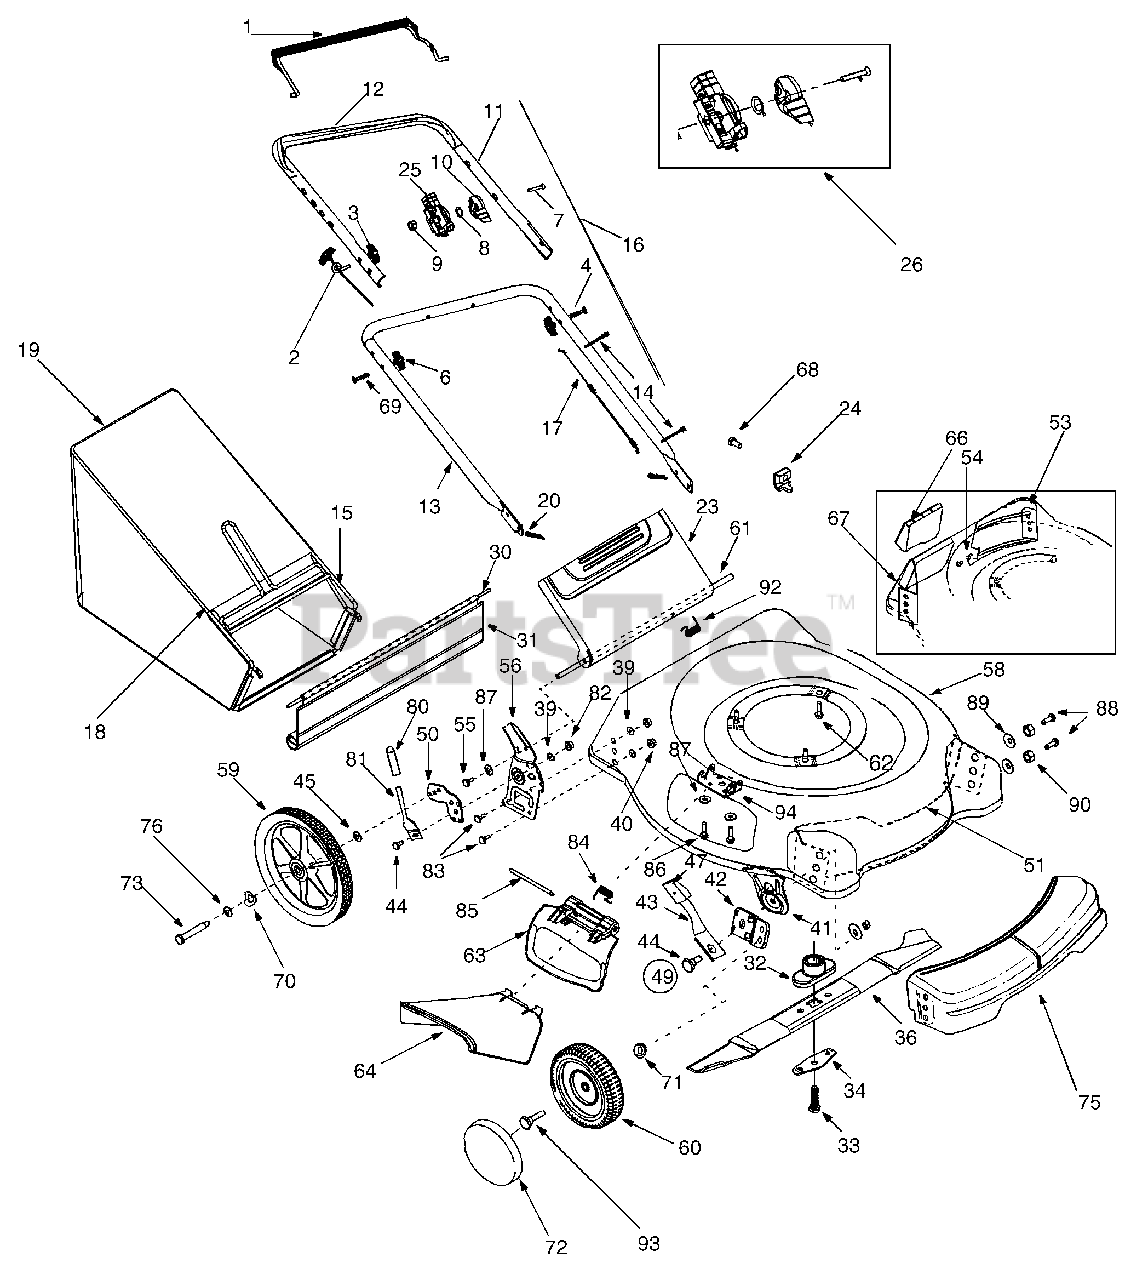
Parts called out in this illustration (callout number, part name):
2	Rope Guide
3	Handle Knob
4	Curved Hd. Bolt 5/16-18 x 2"
6	Hand Knob
7	Oval C-Sunk Screw
8	Spring Washer
9	Hex Lock Nut 1/4-20 Thd.
10	Throttle Lever
14	Cable Tie
16	Control Cable—40"
17	Throttle Control Wire-60"
19	Grass Bag Ass'y w/o logo
20	Internal Cotter Pin
25	Throttle Body
26	Throttle Box Comp.
30	Wire Rod
31	Rear Flap
32	Blade Adapter Kit
33	Hex Bolt 3/8-24 x 1.5"
34	Blade Bell Support
36	Mulching Blade
39	Bell Washer .39" I.D. x 1.38"
40	Hex Nut 3/8-16 Thd.
41	Height Adj. Plate
43	Spring Lever: Front Wheel
44	Shoulder Bolt .5" Dia. x .357"
45	Bell Washer.38" I.D. x .88"
47	Spring Lever Knob
49	Height Adj. Assembly Comp.-R.H.
50	Pivot Bar—R.H.
54	Torx Mach. AB-Tap Scr.
55	Hex Screw TT
56	Handle Bracket Assembly-R.H.
59	Rear Wheel Ass'y.
60	Front Wheel Ass'y.
61	Chute Door Pivot Rod
62	Sems Screw TT 3/8-16 x 1
63	Mulching Plug (Hinged)
64	Chute Deflector
68	Hex Washer Hd. Screw
69	Carr. Bolt 5/16-18 x 2.0
70	Wave Washer
71	Spring Washer
72	Hub Cap: Radial Yellow
73	Rear Axle Bolt
75	Front End Cover: Yellow
76	Flat Washer
80	Spring Lever: Rear Wheel
81	Height Adj. Lever
82	Hex Flange Lock Nut 3/8-16
84	Torsion Spring
85	Hinge Pin
86	Tapp Scr. 1/4-20 x .500
87	Bell Washer .265 x .75 x .062
88	Hex Screw 3/8-16 x .75
89	Bell Washer .39 x 1.13 x .062
90	Hex Nut 3/8-16
92	Torsion Spring
93	Front Axle Bolt
